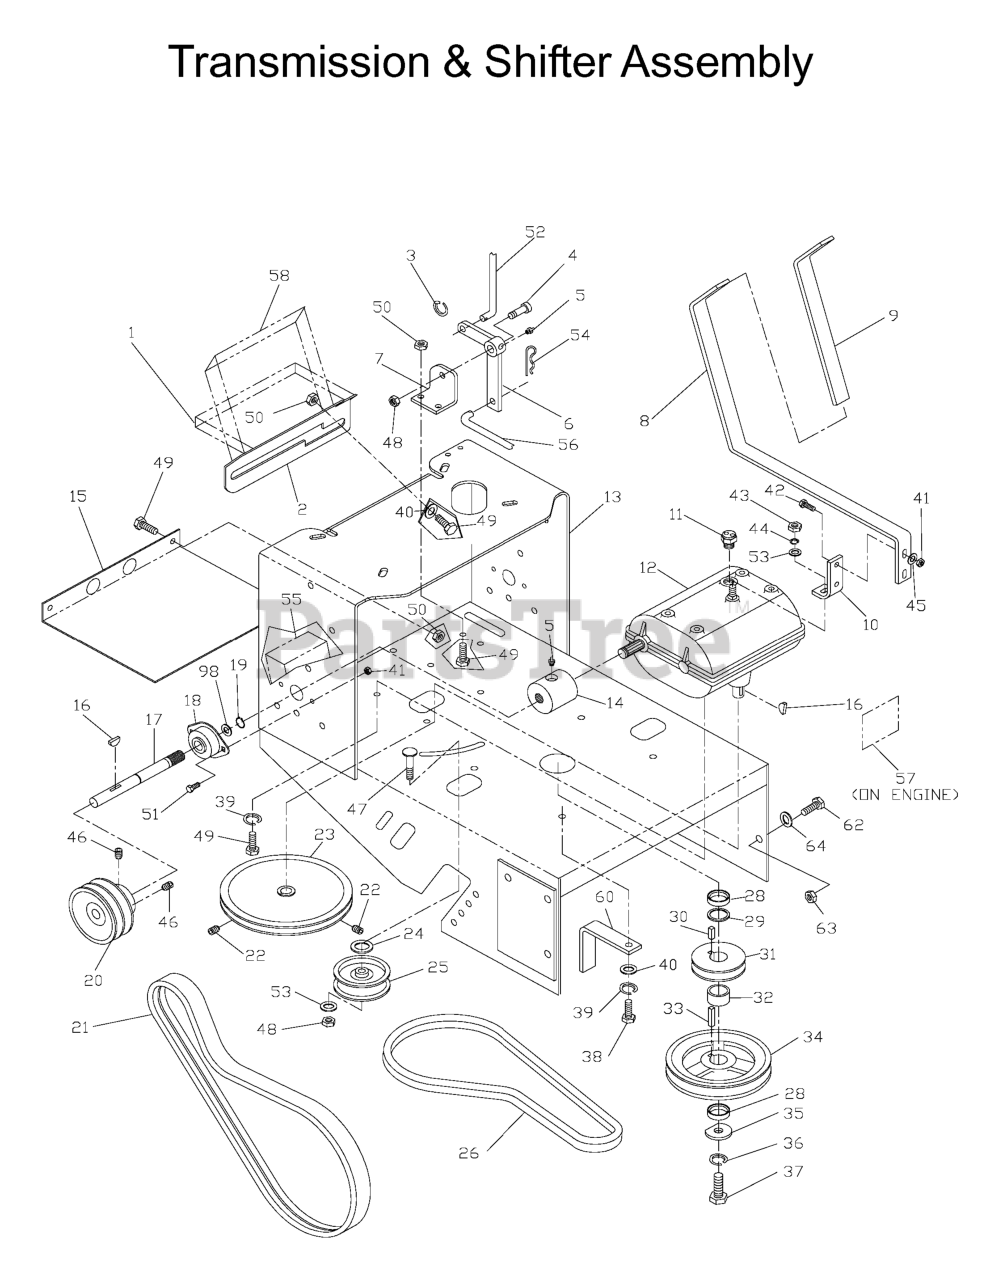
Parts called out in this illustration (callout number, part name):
1	DECAL, SHIFTER
2	SHIFTER PLATE
4	SB 12C X 34
5	ZERK
8	SHIFTER ARM
9	SHIFTER GRIP
10	SHIFTER BRACKET
11	SWITCH, TRANS
12	TRANSMISSION WB
13	REAR DECK W/DECALS
15	LOWER BELT SHIELD
16	KEY, #9 WOODRUFF
17	DRIVE SHAFT
19	RETAINER RING
20	PULLEY, DRIVE (36 & 48)
21	BELT, DRIVE 36/48
22	SETSCREW, 1/4-20 NYLOC
23	PULLEY, INPUT
24	WASHER 1/2 FLAT
25	IDLER PULLEY
26	BELT, TRANSMISSION
27	BELT GUIDE
29	BUSHING, 10GA MACHINERY
30	SQUARE KEY - 1/4 X .5
33	KEY 1/4 SQ X 1 1/8
34	PULLEY, ENGINE
35	SPINDLE WASHER
36	WASHER 7/16 LOCK
37	HCS 7/16F X 1 1/2
38	HCS M8-1.25 X 30MM
39	WASHER.LOCK.HVY.HLCL.SPR.5/16
40	WASHER 5/16 FLAT
41	NUT 1/4C CENTER LOCK
42	HCS 1/4C X 1
44	SLW 3/8 STD
45	WASHER 1/4 FLAT
46	SET SCREW 5/16 NYLOC
47	RHSNB 3/8C X 2
48	NUT 3/8C CENTERBLOCK
49	HCS 5/16C X 3/4
50	NUT 5/16C CENTERLOCK
51	HCS 1/4C X 5/8
53	WASHER 3/8 FLAT
54	HAIRPIN #4
55	DECAL, BELT DRIVE
56	BLADE ROD 36"
57	DECAL, EXHAUST
58	DECAL, CLUTCH
59	BUSHING
60	BELT GUIDE - LONG
61	BELT GUIDE, SHORT
62	HCS 7/16C X 1 1/2
63	NUT 7/16C CENTERLOCK
64	WASHER 7/16 FLAT ZD
539102149	DRIVE BELT (32)
539102154	DRIVE PULLEY (32)
